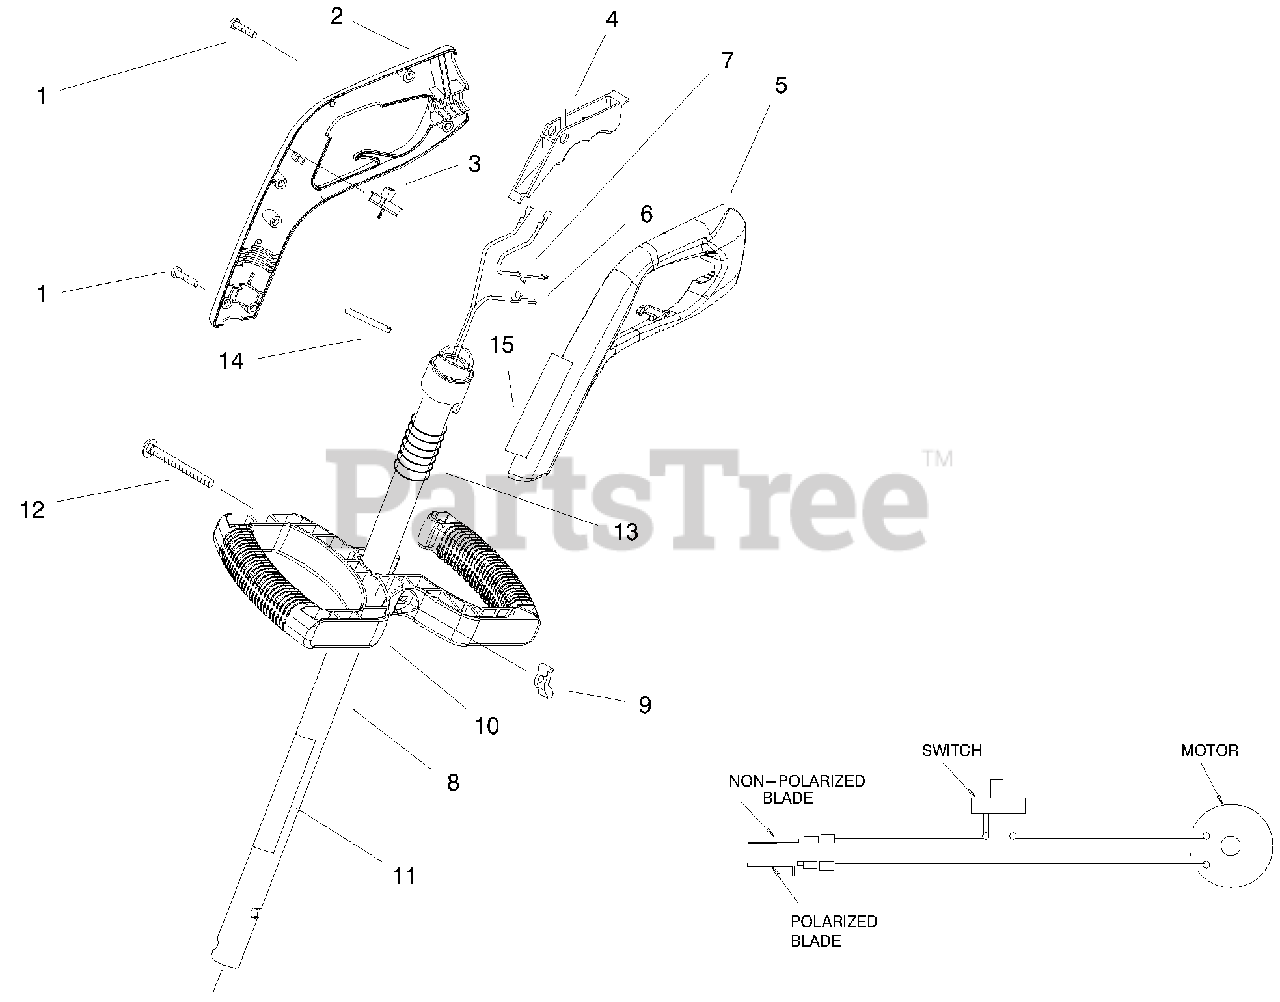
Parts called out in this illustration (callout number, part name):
1	SCREW-PPH
2	Handle-RH
5	Handle-LH
6	HARNESS-WIRE
7	WIRE ASM-JUMPER
8	TUBE ASSEMBLY
9	1/4"-20 STAMP WNG NUT
10	MID-HANDLE
11	DECAL-WARNING
12	SCREW-CARR.25-20 X 2.50
13	SPRING-TUBE
14	PIN-HANDLE
15	DECAL-INFORMATION
